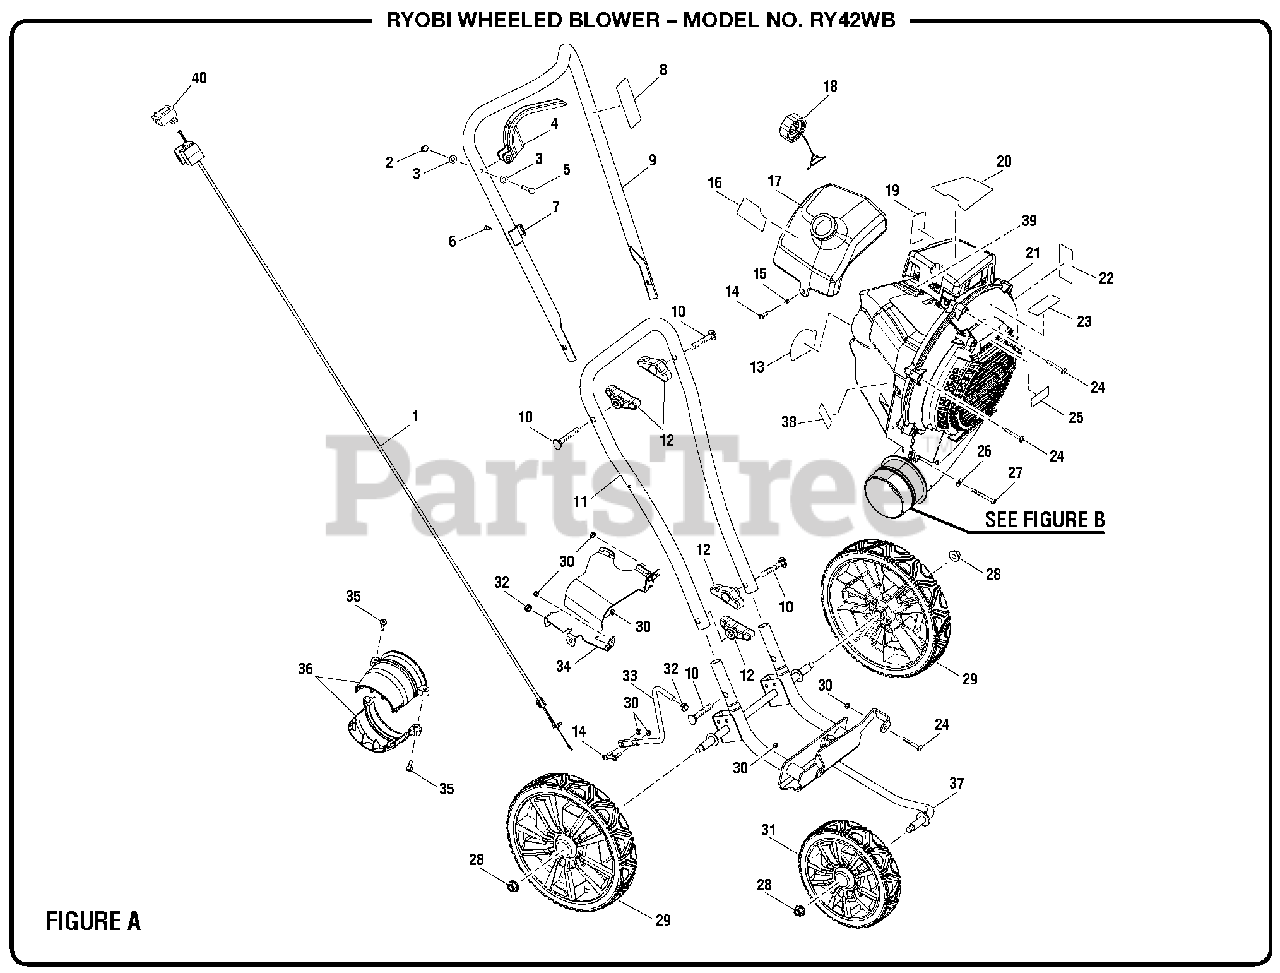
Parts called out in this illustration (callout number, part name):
1	Lead Wire and Throttle Cable Assembly
2	Retaining Ring
3	Fiber Washer (OD12.5 x ID6.35 x 2t)
6	Screw (8-16 x 1/2 in., Pan Hd.)
7	Cable Clip
8	Warning Icon Label (Handle)
9	Upper Handle Assembly
10	Carriage Bolt (M8 x 60 mm)
11	Center Handle
12	Knob Assembly
13	Model/Performance Label
14	Screw (M5 x 16 mm, T25 Torx Pan Hd.)
16	E85 Label
17	Fuel Tank Assembly
18	Fuel Cap Assembly
19	Choke Label
20	Starting Instructions Label
21	Power Head Assembly
22	Hot Surface Label
23	Warning Icon Label (Inlet)
24	Screw (M5 x 35 mm, T25 Torx Pan Hd.)
25	Logo Label (Ryobi)
26	Washer (OD14 x ID5.1 x 1.4t)
27	Cap Screw (M5 x 45 mm, T25 Torx Soc. Hd.)
28	Lock Nut (3/8-16 in.)
29	Rear Wheel Assembly
30	Lock Nut (M5)
31	Front Wheel Assembly
32	Lock Nut (M8)
33	Support Rod
35	Screw (10-14 x 3/4 in., Tri-Round T.F.)
37	Frame Assembly
38	Combustion Label
39	Fuel Line Padding
40	Stop Switch (Momentary Contact)
